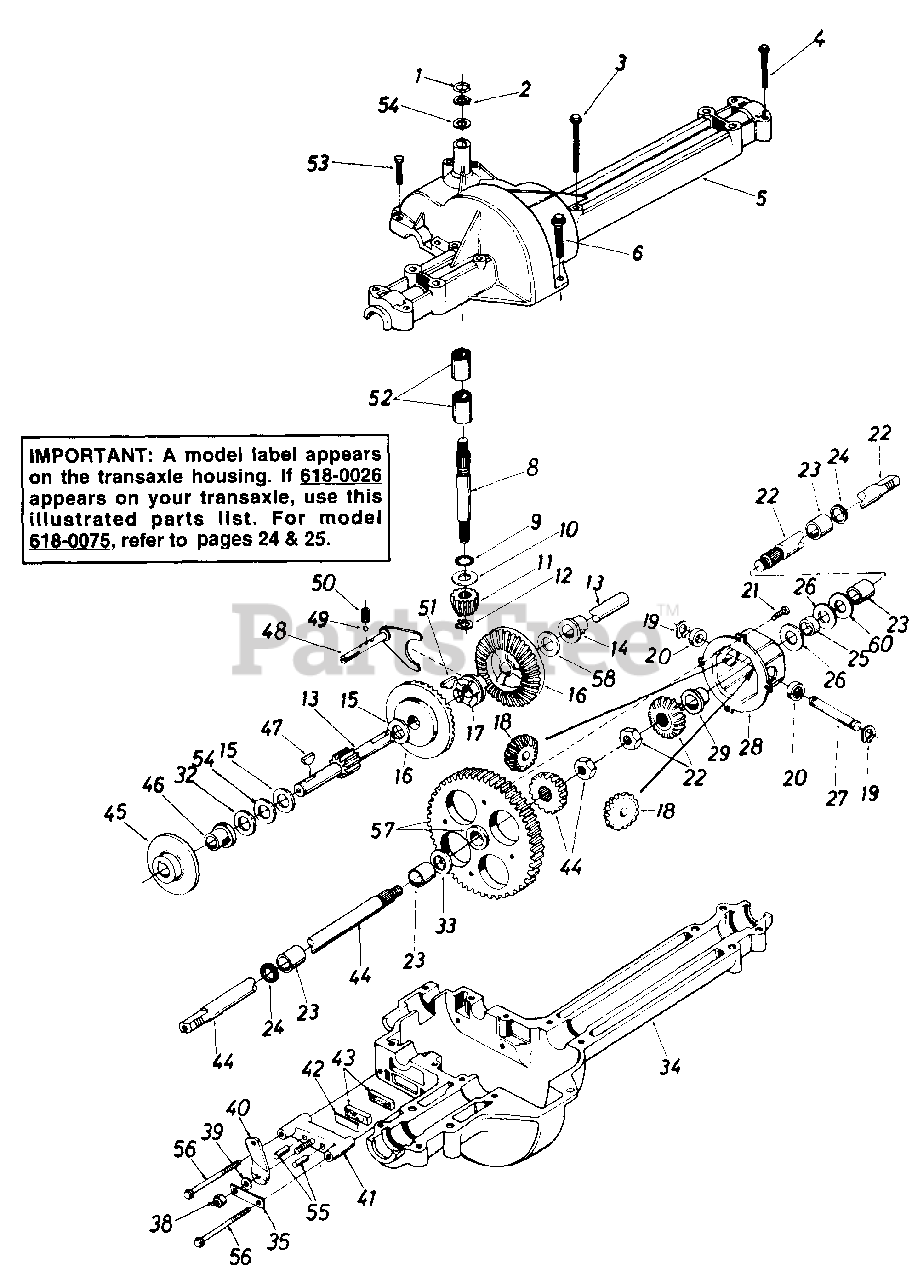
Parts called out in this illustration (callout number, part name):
2	Retaining - Ring
3	Hex Bolt 1/4-20 x 1.75" Lg.
4	Hex Tap Scr. 1/4-20 x 1.25" Lg.
5	Upper Housing
6	Hex TT-Tap Scr. 1/4-20 x .75" Lg.
9	Square Seal 5/8" I.D.
10	Thrust Washer 5/8" I.D. x 1.25" O.D.
11	Pinion Input 14T
12	Retaining Ring
14	Flange Brg. 5/8" I.D. x 3/4" Lg.
15	Fl-Wash. 5/8" I.D. x 1.25"
16	Bevel Gear 42T
17	Clutch Collar
18	Miter Gear 15T (H.D.)
19	Snap Ring
20	Thrust Bearing
21	Pan Head Scr. 1/4-20 x .50" Lg. w/Patch
22	Axle R.H. Ass'y.
23	Sleeve Bearing 3/4" I.D. x 1.0" Lg.
24	Oil Seal 3/4" I.D.
26	Fl-Wash. .760" I.D. x 1.5" O.D.
28	Differential Can Ass'y.
32	Thrust Wash. 5/8" I.D. x 1" O.D. x .025" Thk.
33	Fl-Wash. .760" I.D. x 1.5" O.D.
34	Lower Housing
35	Anti-Rotation Brkt.
38	Hex Nut 5/16-24 Thd.
39	Fl-Wash. .344" I.D. x .875" O.D.
40	Actuating Arm
41	Brake Yoke
42	Puck Plate
43	Brake Puck
44	Axle L.H. Ass'y.
46	Flange Bearing 5/8" I.D. x 15/16" Lg.
47	Woodruff Key 3/16 x 5/8 HT
48	Shift Fork Ass'y.
49	Ball Detent .250" Dia.
50	Spring Detent
51	#9 Hi-Pro Key 3/16" x 3/4" Dia. HT
52	Needle Brg. 5/8" I.D. x 1/2" Lg.
53	Hex Bolt 1/4-20 x 1.00" Lg.
54	Fl-Wash. 5/8" I.D. x 1" O.D. x .020 Thk.
55	Actuating Pin 5/16" Dia.
56	Hex Wash Hd. Self-Tap Scr. 1/4-20 Thd.
57	Differential Gear 72T Ass'y. w/Bearing
58	Fl-Wash. 5/8" I.D. x 1" O.D. x .020 Thk.
60	Fl-Wash. .76" I.D. x 1.5" O.D. x .010" Thk.
